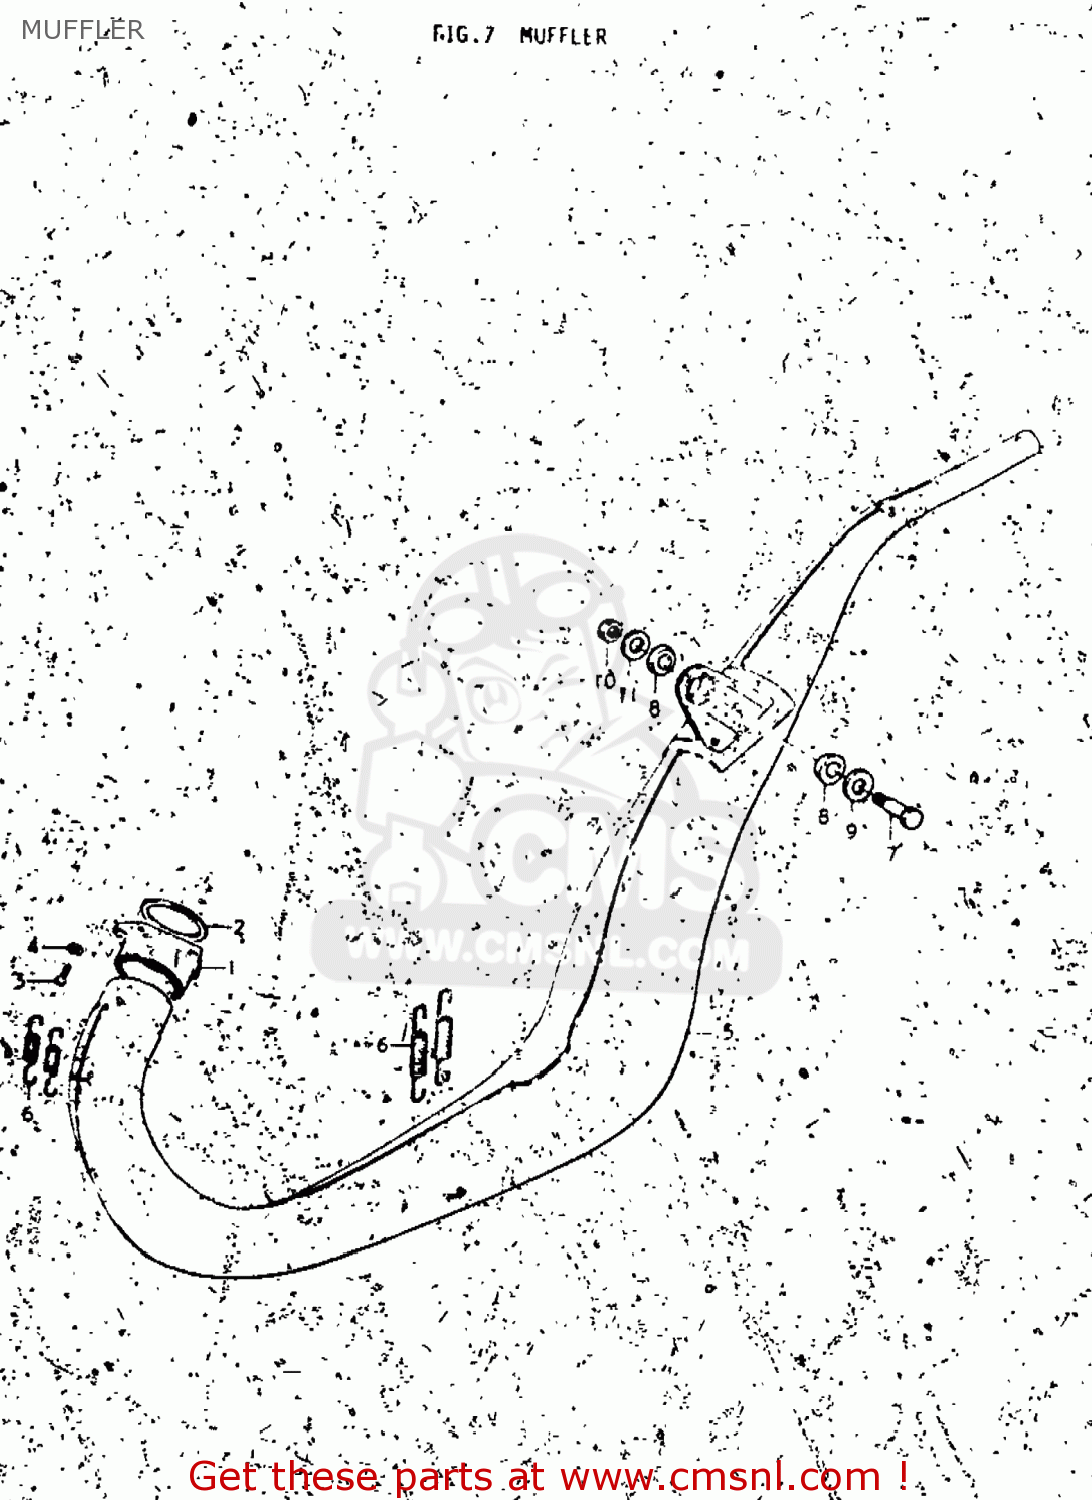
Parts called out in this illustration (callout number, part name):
1	FLANGE,EXHAUST PIPE
2	GASKET,EXHAUST PIPE (MCA)
3	SCREW
4	LOCK WASHER
5	BODY,MUFFLER
6	SPRING
7	BOLT
8	CUSHION
9	WASHER
10	NUT
11	BRACKET, MUFFLER STOPPER
12	LOCK WASHER
13	BOLT
14	CUSHION(11.5X22X20)
15	SPRING
16	MUFFLER ASSEMBLY
17	PIPE,MUFFLER BAFFLE
18	SCREW(6X8)
19	LOCK WASHER
20	CONNECTOR,MUFFLER
21	CLAMP
22	SCREW
23	DAMPER,MUFFLER SUPPORT
24	BOLT
25	NUT
26	LOCK WASHER
27	WASHER
28	BOLT
29	LOCK WASHER
30	WASHER
31	SPRING
